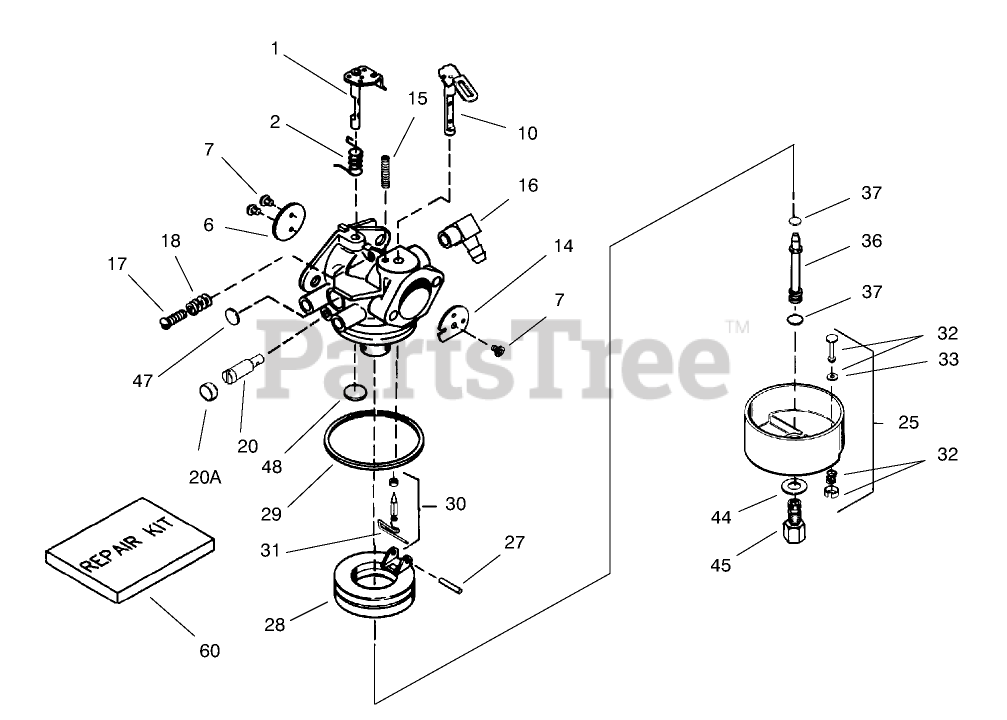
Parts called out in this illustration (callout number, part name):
1	Throttle-Shaft Lever Asm
2	Spring-Return, Throttle
6	Throttle Shutter
7	Screw-Shutter
10	Choke Shaft Lever ASM
14	Choke Shutter
15	Spring-Positioning, Choke
16	Fitting-Fuel
17	Screw-Throttle Crack and Idle Speed
18	Spring-Tension
20	Screw-Restrictor, Idle
20A	Cap-Screw, Idle Restrictor
25	Float Bowl ASM (Incl. Ref. #32 and 33)
25	Float Bowl Asm. (Incl. Ref. # 32, 33)
27	Shaft-Float
28	Float
29	O Ring-Bowl, Float
30	Inlet Needle, Seat Clip Assy. (Incl. No. 13)
31	Clip-Spring
32	Plunger Assy., Drain (Incl. Ref. 18)
33	Gasket-Plunger, Drain
36	Tube-Nozzle, Main
37	O-Ring, Main Nozzle Tube
40	High Spee Bowl Nut.
44	Washer-Bowl Nut
47	Plug-Welch, Idle Mixture Well
48	Plug-Welch, Atmospheric Vent
60	Kit-Repair
